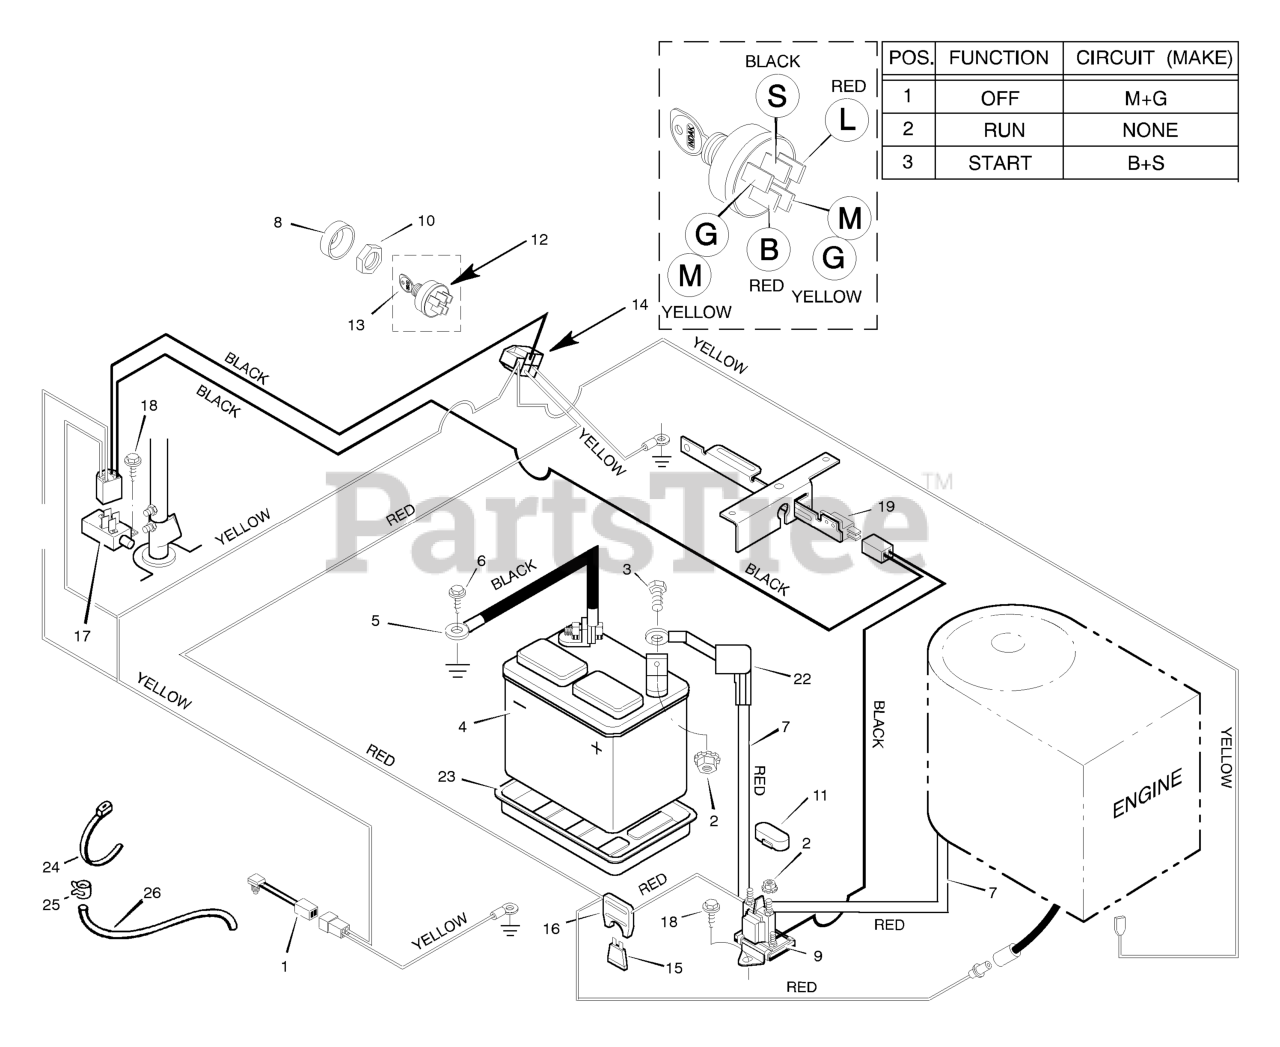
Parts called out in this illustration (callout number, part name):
1	Switch, Seat Sensor
2	Locknut
4	Battery
5	Cable, Battery Ground
7	Cable, Red Battery
8	Cap, Ignition
9	Solenoid
10	Nut, Hex
11	Cover, Solenoid
12	Switch, Ignition
13	Key, Ignition
14	Harness, Chassis Wire
16	Holder, Fuse
17	Switch, Limit
19	Switch, Limit
22	Cover, Terminal
23	Tray, Battery
24	Strap, Tie
26	Drain, Tube
